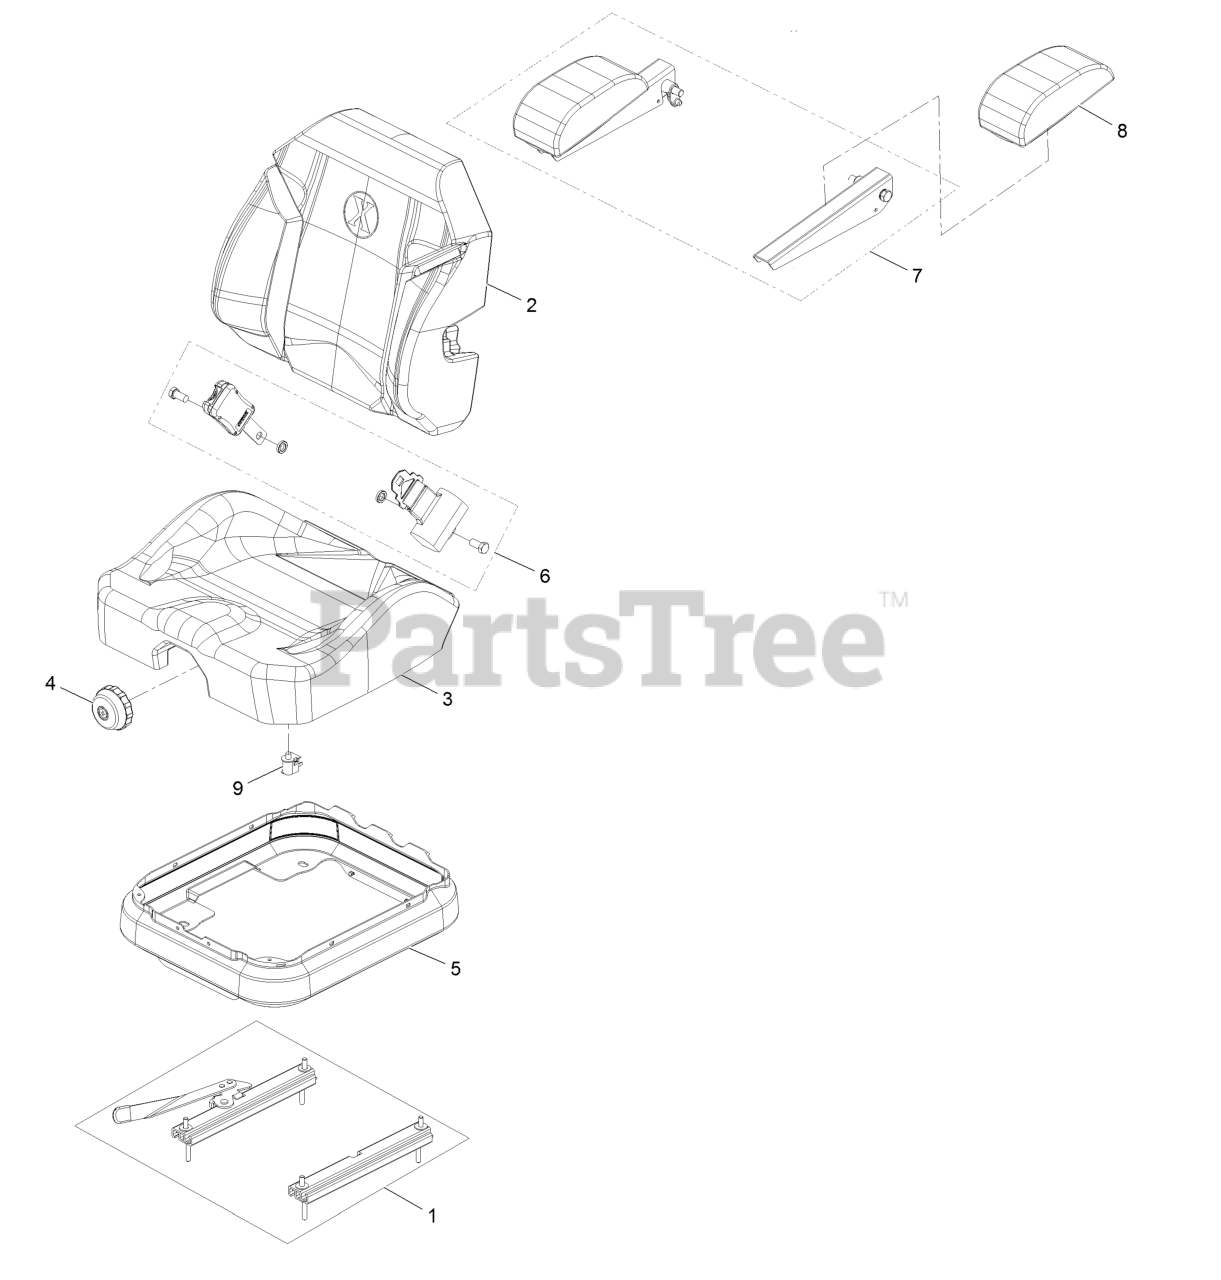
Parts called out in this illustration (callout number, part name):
1	Seat Track Set
2	Cover-Back 311463Vn500
3	Cover-Cushion 311464Vn500
4	Knob-Adjuster
5	Cover-Suspension Bellows
6	Seat Belt Service Kit
7	Kit-Arm Rest Set
8	Kit-Arm Rest Pads
